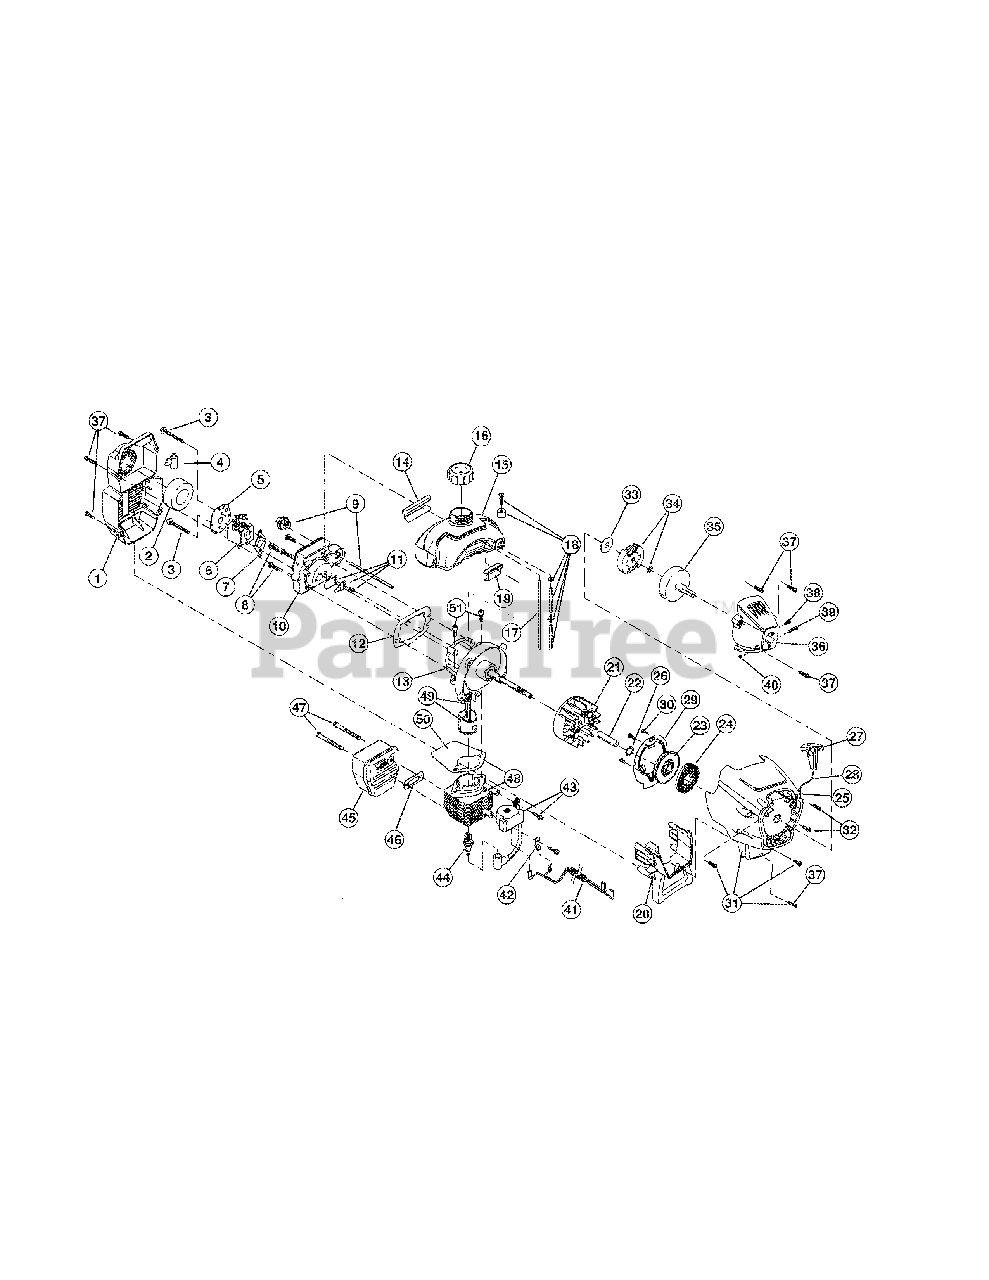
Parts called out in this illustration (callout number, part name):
1	Air Cleaner Assembly (includes 2 & 37)
2	Air Cleaner Filter
3	Carburetor Mounting Screw Assembly
4	Choke Extension
5	Choke Plate
6	Carburetor Assembly (includes 7 & 18)
7	Carburetor Gasket
8	Carb Mount Screw
9	Primer and Hose Assembly
10	Carb Mount Assembly (includes 8, 11 & 12)
11	Reed Assembly
12	Carburetor Mount Gasket
13	Crank Case Service Assembly (includes 8)
14	Rear Mounting Pad
15	Fuel Tank Assembly (includes 16-18)
16	Fuel Cap Assembly
17	Fuel Return Line
18	Fuel Line Assembly
19	Front Mounting Pad
20	Shroud Extension & Stand (includes 37)
21	Flywheel Assembly
23	Recoil Pulley Assembly (Includes 26)
24	Recoil Spring
25	Rope Guide
26	Palnut
27	Pull Handle
29	Pressure Plate Assembly (includes 30)
30	Plate Screw
31	Starter Housing Assembly (includes 23-30, 32 & 37)
32	Housing Screw
33	Clutch Washer
34	Clutch Rotor Assembly
35	Clutch Drum Assembly
36	Clutch Cover Assembly (includes 37-40)
37	Cover Screw
38	Anti-Rotation Screw
39	Clamping Screw
40	Clamping Nut
41	Wire Leads and Sleeve
42	Ground Tab
43	Module Assembly (includes 42)
44	Spark Plug
45	Muffler Assembly (includes 46 & 47)
46	Exhaust Gasket
47	Muffler Mounting Bolt Assembly
48	Cylinder Assembly (includes 50 & 51)
49	Piston and Rod Assembly
50	Cylinder Gasket
51	Cylinder Bolt
